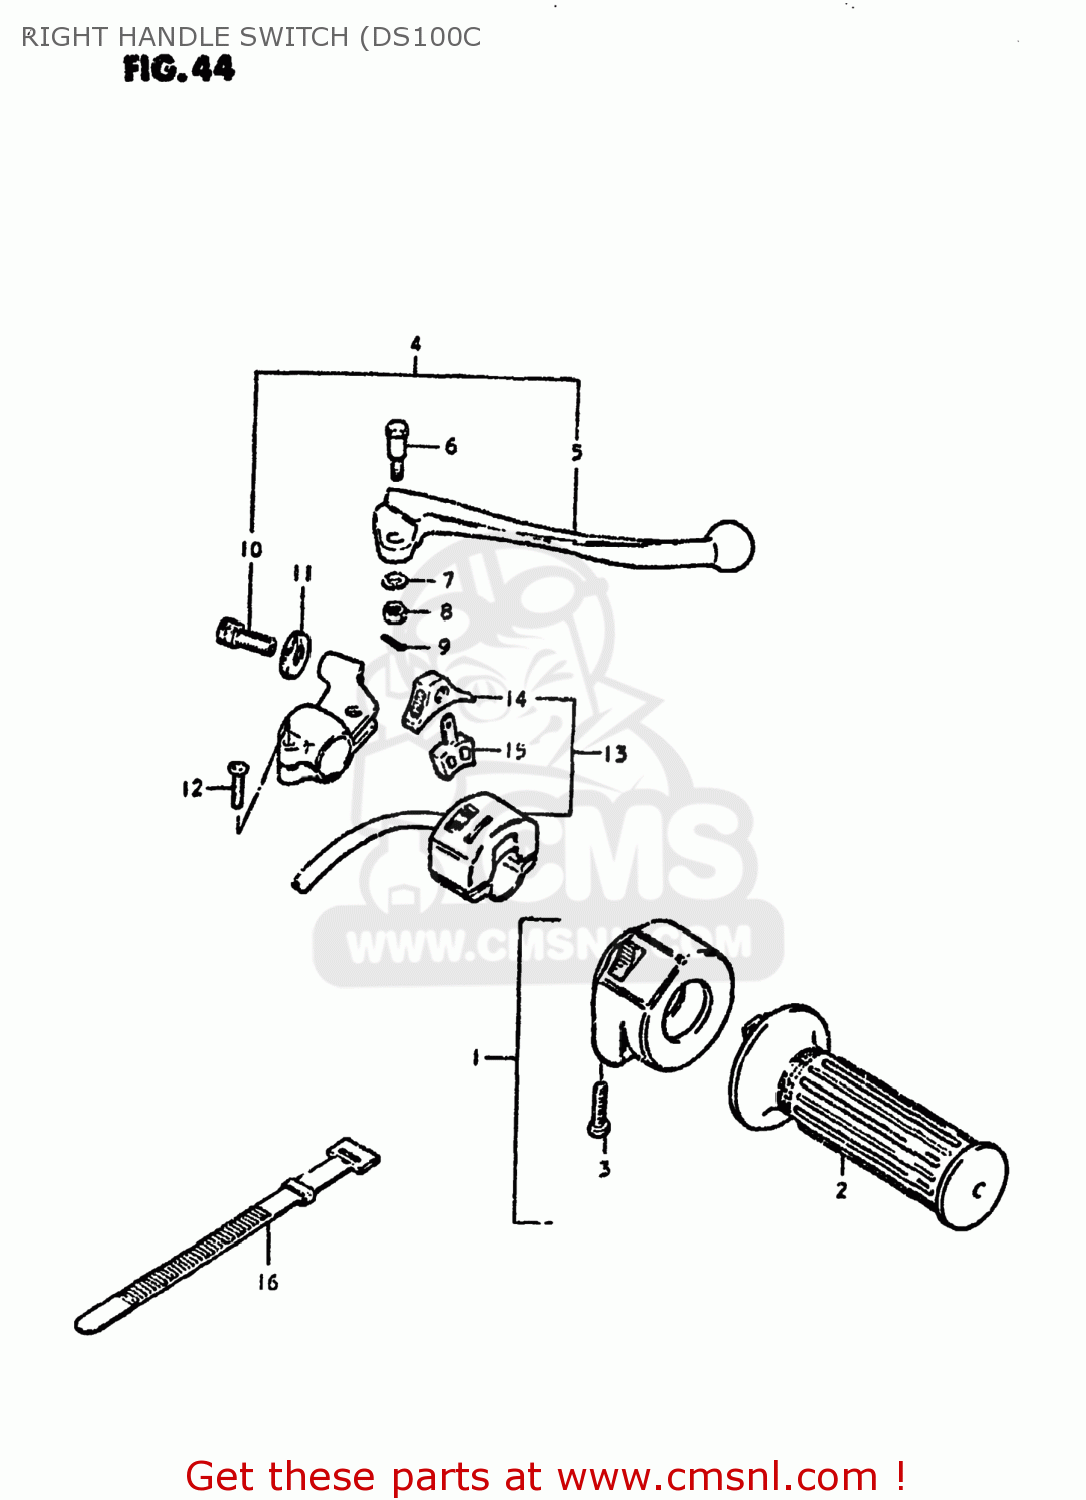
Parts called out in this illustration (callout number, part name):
1	GRIP ASSEMBLY,THROTTLE
2	GRIP,THROTTLE
3	SCREW
4	LEVER ASSEMBLY,BRAKE
5	LEVER,BRAKE
6	BOLT,LEVER
7	LOCK WASHER
8	NUT 6MM
9	COTTER PIN
10	ADJUSTER,CABLE
11	NUT,CABLE ADJUSTER
12	SCREW
13	SWITCH ASSEMBLY,LIGHTING
14	KNOB,HANDLE SWITCH
15	BLOCK,LIGHTING/DIMMER
16	CLAMP(L:120)
